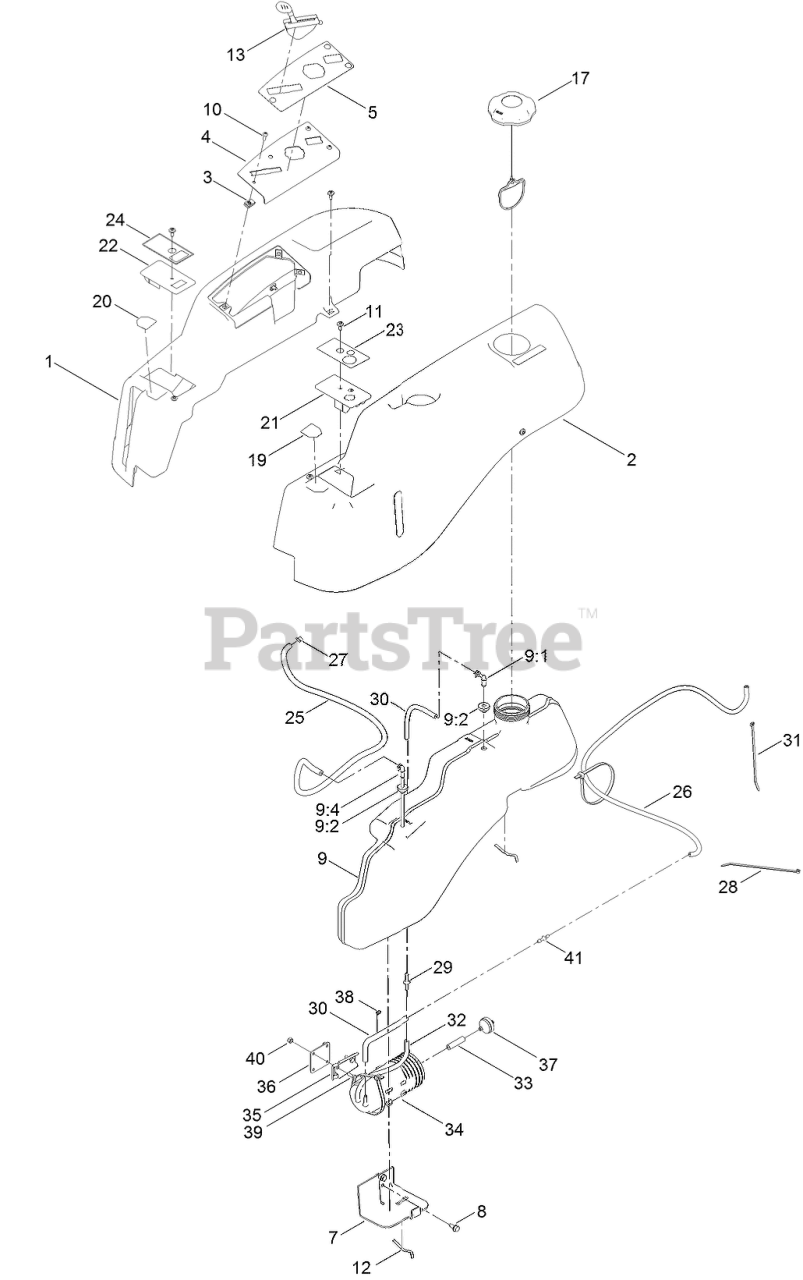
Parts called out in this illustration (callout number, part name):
1	POD-RH
2	POD-LH
4	PLATE-CONTROL
5	DECAL-PANEL, CONTROL
7	SUPPORT-TANK, FRONT
8	SCREW-HWHTF
9	FUEL TANK ASM
9:1	CONNECTOR-ELBOW, 90 DEG
9:2	BUSHING
9:4	FITTING-PLASTIC
10	SCREW-PRH
11	SCREW-SHOULDER
12	SPRING
13	CABLE-THROTTLE (45.0 IN)
17	CAP-FUEL, RATCHETING
19	DECAL-NMIR
20	DECAL-CONTROL, PEDAL
21	COVER-LH
22	COVER-RH
23	DECAL-KEYCHOICE
24	DECAL-BRAKE, PARKING
25	HOSE-FUEL
26	HOSE-FUEL
27	CLAMP-HOSE
28	TIE-CABLE
29	ADAPTOR-ORIFICE
30	HOSE-FUEL
31	TIE-CABLE
32	HOSE-FUEL
33	HOSE-FUEL
34	CANISTER-CARBON, 800CC
35	BRACKET-CANISTER, CARBON
36	PLATE-ADAPTER
37	FILTER-FUEL, INLINE
38	CARTRIDGE-VALVE, CHECK
39	SCREW-HH
40	NUT-LOCK, NI
41	FITTING-STRAIGHT
